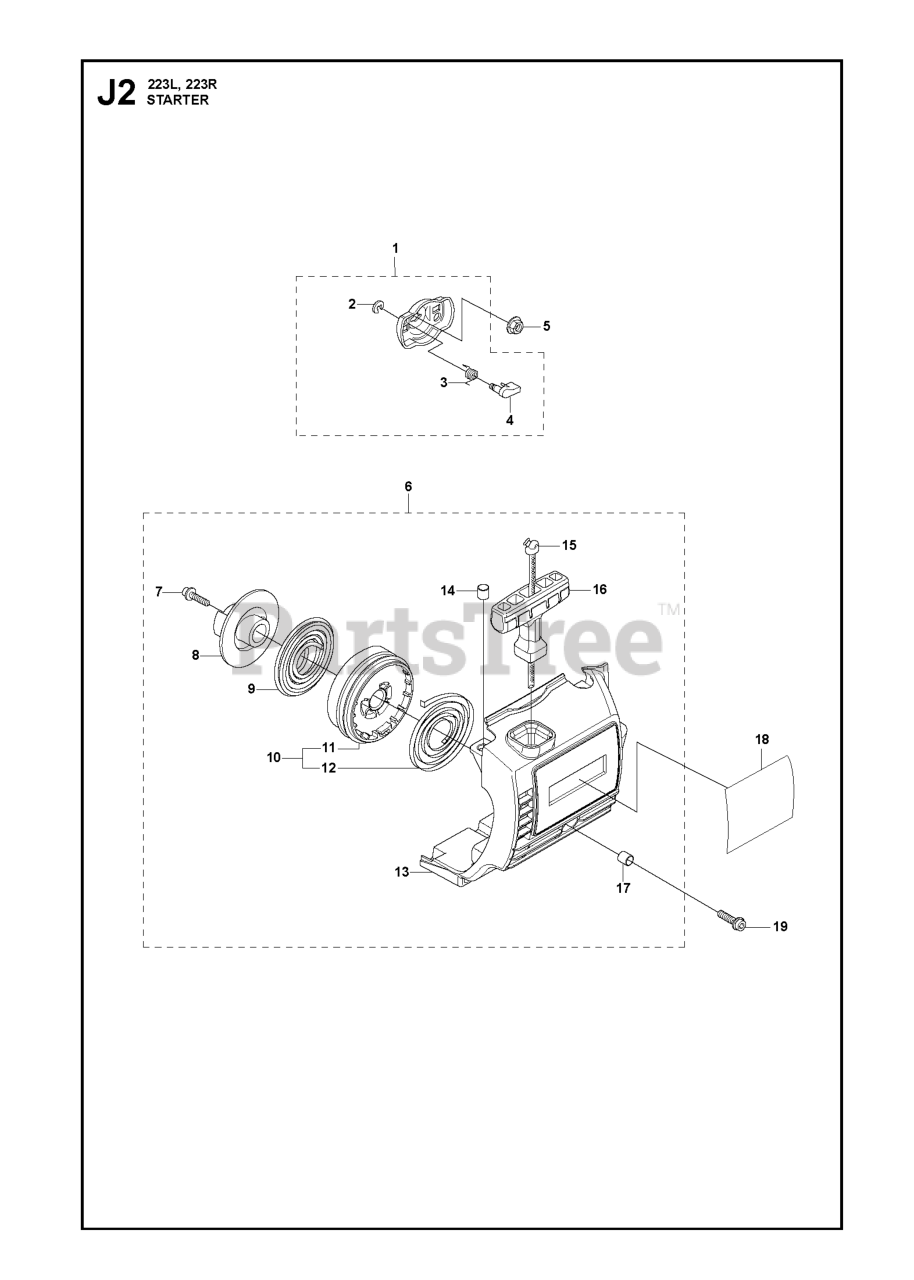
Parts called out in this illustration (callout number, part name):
1	PAWL ASSY COMPLETE
4	STARTER PAWL
5	FLANGE NUT
6	STARTER DEVICE CPL
8	WHEEL
9	BALANCING SPRING
10	STARTER PULLEY
11	STARTER PULLEY
13	RP STARTER HOUSING
14	%SPACER SLEEVE
15	STARTER ROPE
16	STARTER HANDLE
17	%SPACER SLEEVE
18	223 STARTER HOUSING DECAL
18	LABEL STARTING DEVICE
